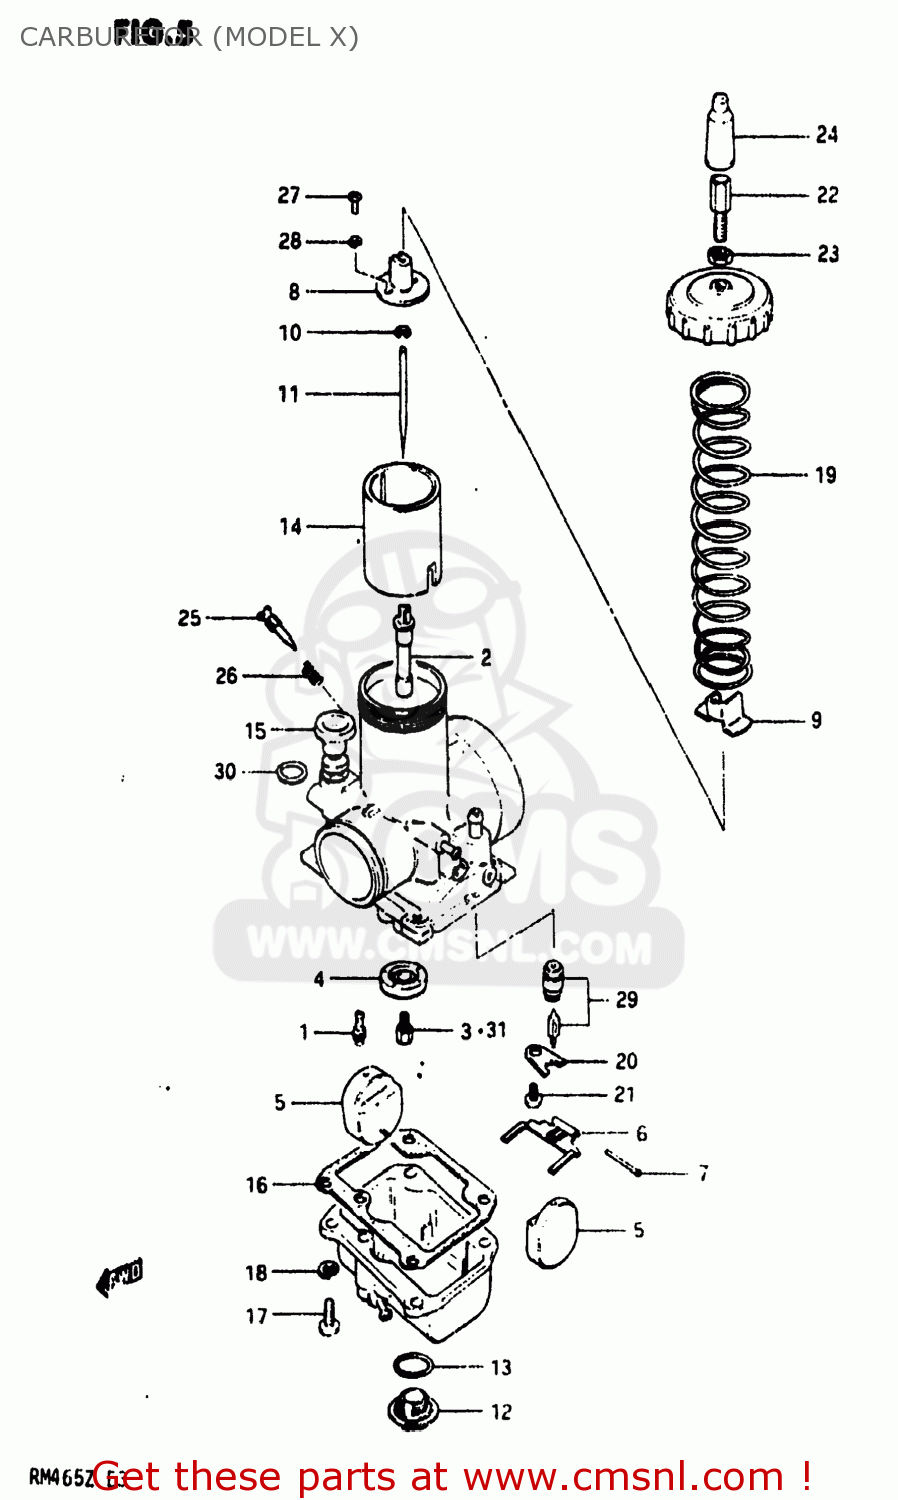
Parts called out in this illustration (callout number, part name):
1	JET,PILOT
2	JET,NEEDLE
3	JET
4	RING,MAIN JET FIXING
5	FLOAT
6	ARM,FLOAT
7	PIN,FLOAT
8	CONNECTOR
9	COVER,HOLDER
10	CLIP
11	NEEDLE JET
12	PLUG
13	O RING(D:1.5,ID:19.5)
14	VALVE,THROTTLE
15	VALVE ASSEMBLY,STARTER
16	GASKET,FLOAT CAHMBER (NAS)
17	SCREW
18	LOCK WASHER
19	SPRING
20	PLATE
21	SCREW 4X6
22	ADJUSTER,CABLE
23	NUT
24	CAP,CABLE ADJUSTER
25	SCREW,PILOT AIR
26	SPRING
27	SCREW
28	LOCK WASHER
29	VALVE ASSEMBLY,NEEDLE
30	O-RING
31	JET
